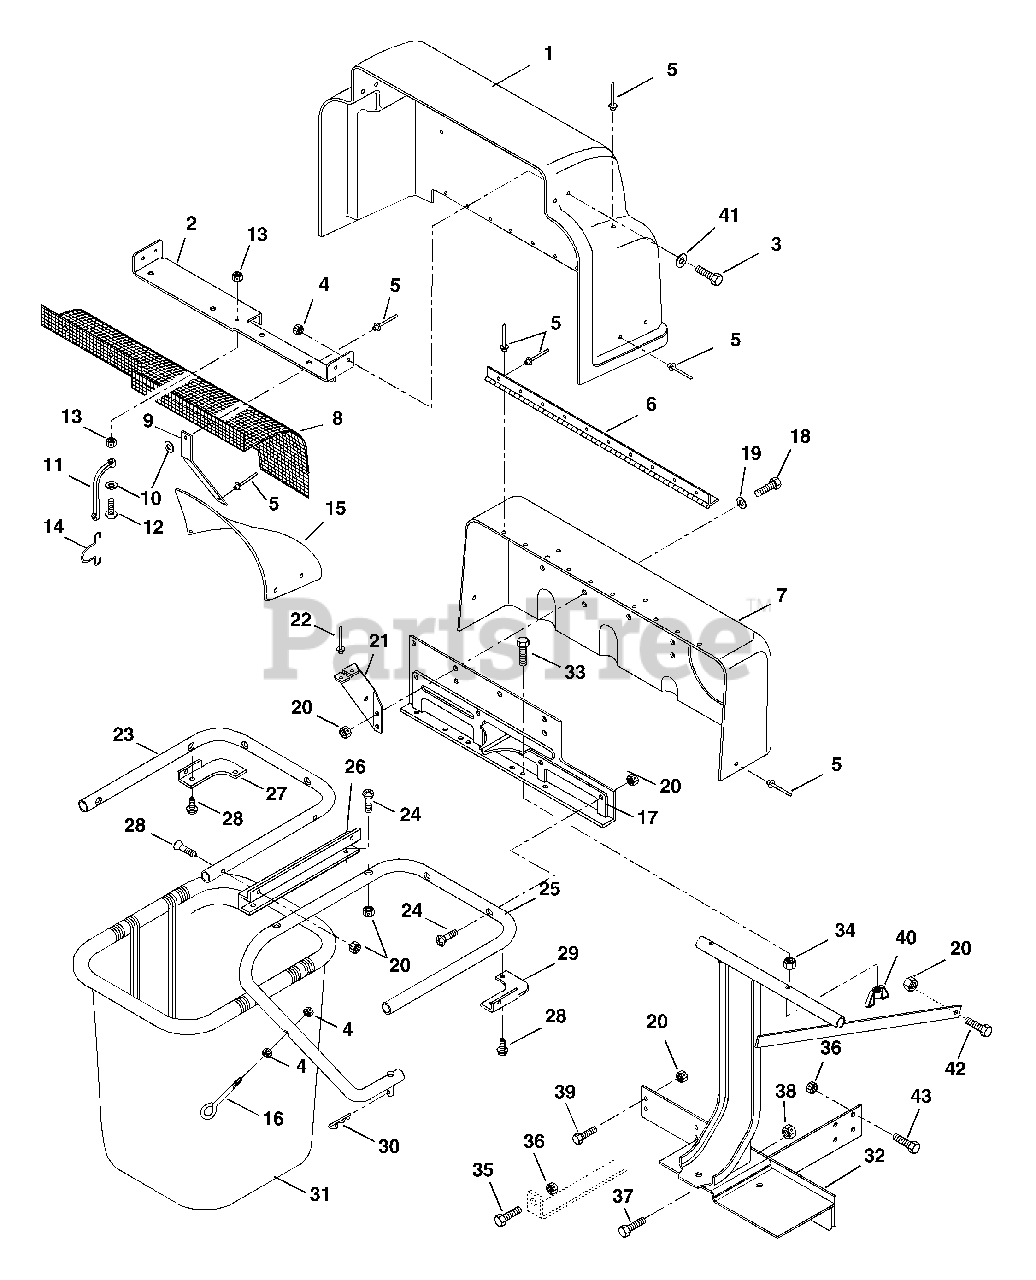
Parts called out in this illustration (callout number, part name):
1	HINGED COVER W/DECALS
2	COVER BRACKET
3	@BLT-HEX .25-20X.50 GR5 YWZC
4	@NUT-LK-CTR .25-20 YWZC
5	RVT-POP .187X.402 DOME ST
7	STATIONARY COVER
8	SCREEN, BAGGER
10	@WSHR-FL-STL.219X.50X.049 YWZC
11	BATTERY STRAP
12	SCR-MCH 10-24X.88 SLRH YWZC
13	@NUT-LK-NYL 10-24 W/INSRT YWZC
16	EYEBOLT
17	MOUNTING BRACKET
18	BOLT-HEX.31-18X.875 YWZC GR5
19	WSHR-FL-STL .328X.875X.062YWZC
20	@NUT-LK-CTR .31-18 YWZC
22	RVT-POP.187X.527 DOME ST
23	CENTER TUBE
24	SCR-MCH .31-18 X 1.50 YWZC
25	RIGHT TUBE
26	TUBE BRACKET
27	LH CORNER BRACKET
28	@SCR-TAP .31-18X.50 HWH TR YWZ
29	RH CORNER BRACKET
30	PIN-HAIR INT .08X.38X1.42 YWZC
31	GRASS BAGGER BASKET
32	FRAME, BAGGER
33	BLT-HEX .31-18X1.75 FLTHD YWZC
34	@NUT-HEX .31-18 YWZC
35	@BLT-HEX .38-16X1.25 GR5 YWZC
36	@NUT-LK-CTR .38-16 YWZC
37	@BLT-HEX .50-13X1.00 GR5 YWZC
38	@NUT-LK-CTR .50-13 YWZC
39	@BLT-HEX .31-18X1.00 GR5 YWZC
40	NUT-NYLK WING .312-18 YWZC
41	@WSHR-FL-STL.281X.62X.065 YWZC
42	@BLT-HEX .31-18X1.25 GR5 YWZC
43	@BLT-HEX .38-16X1.00 GR5 YWZC
